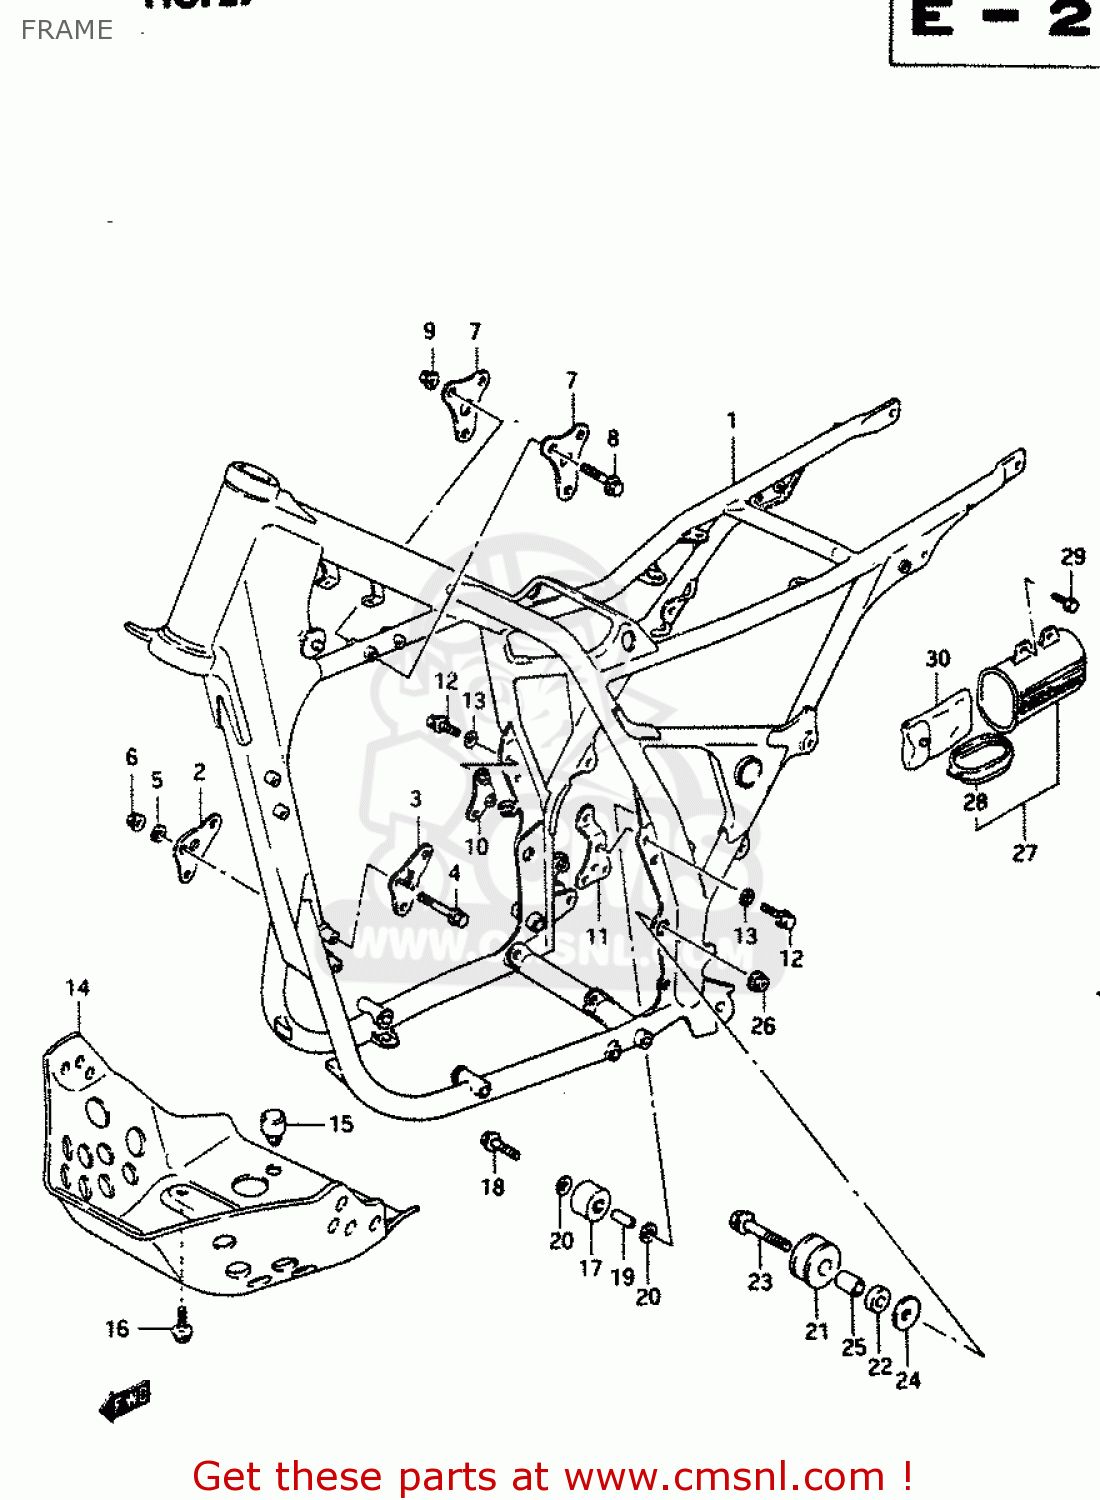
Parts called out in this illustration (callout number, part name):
1	FRAME (BLUE)
2	PLATE, FRONT RH (BLACK)
3	PLATE, FRONT LH (BLACK)
4	BOLT(8X72)
5	WASHER,LOCK
6	NUT
7	PLATE, UPPER (BLACK)
8	BOLT 8X50
9	NUT
10	PLATE, REAR RH (BLACK)
11	PLATE,ENGINE MOUNTING
12	BOLT(8X20)
13	WASHER,LOCK
14	PROTECTOR,ENGINE
15	CUSHION
16	BOLT 8X16
17	ROLLER,CHAIN CONTROL
18	BOLT(8X41)
19	SPACER (8.6X13.8X28)
20	WASHER (8.2X24X1.6)
21	ROLLER,CHAIN CONTROL
22	SPACER,LOWER
23	BOLT 8X50
24	WASHER
25	SPACER(8.6X12X25.5)
26	NUT
27	HOLDER,TOOL
28	CAP,HOLDER
29	BOLT M6X16
30	TOOL ASSY
